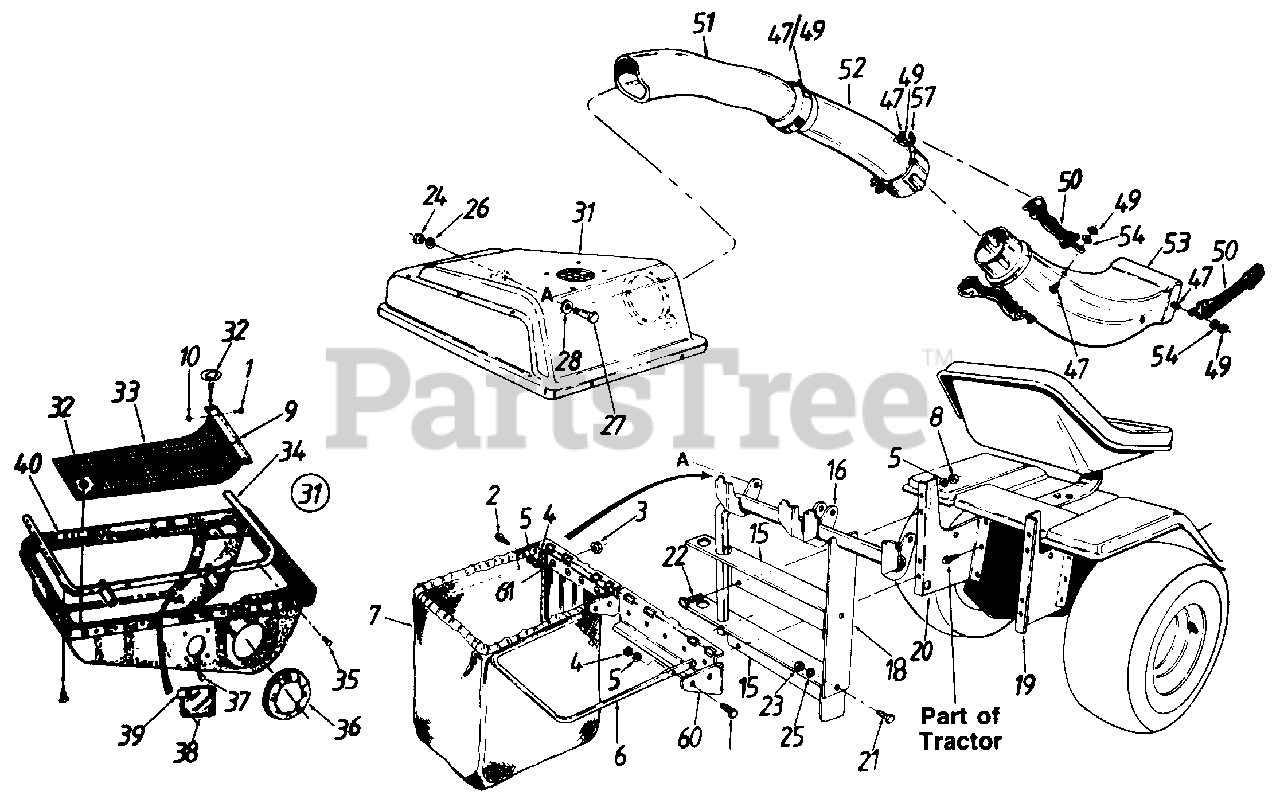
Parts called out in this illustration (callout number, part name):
1	Pop Rivet .188 Dia.
2	Hex Bolt 1/4-28 x .75"
3	Hex Sems Nut #10-24 Thd.
4	Hex Nut 11428 Thd.
5	L-Wash. 1/4" l.D.
6	Catcher Bag Frame
7	Grass Catcher Bag
8	Hex Nut 1/4-20 Thd.
9	Screen Mtg. Brkt.
10	Flat Wash. 1/4" I.D.
15	Catcher Support Tube Mtg. Brkt.
16	Catcher Support Tube Ass'y.
18	Catcher Latch and Support Brkt.
19	Grass Catcher Support Brkt.-R.H.
20	Grass Catcher Support Brkt.-L.H.
21	Hex Bolt 5/16-18 x .75"
22	Hex Bolt 1/4-20 x .62" Lg.-Grade 5
23	Hex Nut 5/16-18 Thd.
24	Hex Nut 3/8-16 Thd.
25	L-Wash. 5/16" I.D.
26	L-Wash. 3/8" I.D.
27	Shld. Bolt 3/8-16 x .50" Dia.
28	Bell-Wash. .505" l.D. x 1.0" O.D.
31	Grass Catcher Cover Ass'y.
32	Twist Fastener
33	Screen
34	Hinge Brkt. Ass'y.
35	Hex AB-Tap Scr. 1/4 x .62"
37	Truss Mach. B-Tap Scr. #10 x .5" Lg.
38	Plastic Plate
39	Speed Nut
40	Grass Catcher Cover
47	Hex Bolt 1/4-20 x .5"
49	Hex Ins. L-Nut 1/4-20 Thd.
50	Retainer Strap Ass'y.
51	Catcher Elbow
52	Catcher Tube
53	Discharge Chute
54	L-Wash. .27" I.D.
57	Retainer Hook Brkt.
60	Bag Frame Hanger Brkt.
61	Truss Mach. Scr. #10-24 x .5" Lg.
